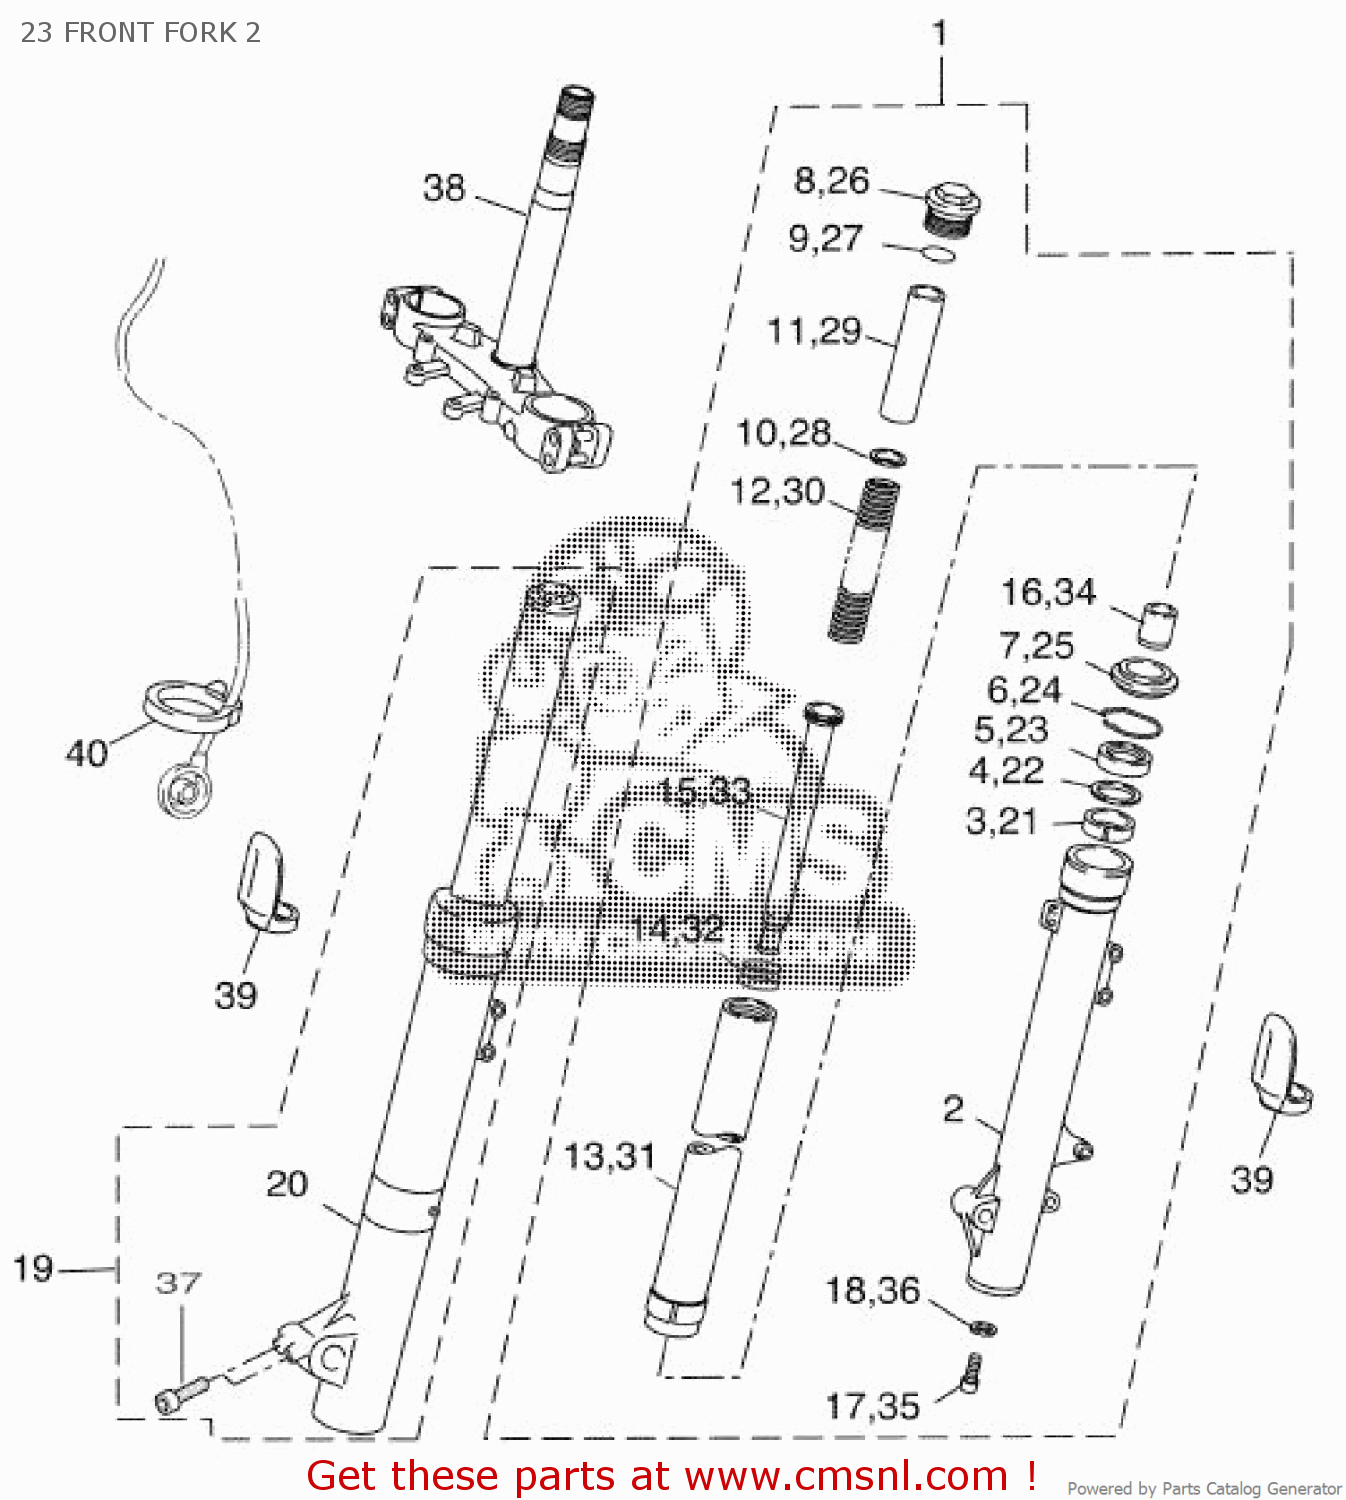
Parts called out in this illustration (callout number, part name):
1	FRONT FORK ASSY (L.H)
2	TUBE, OUTER (LEFT)
3	METAL, SLIDE 1
4	WASHER, OIL SEAL
5	OIL SEAL
6	CLIP, OIL SEAL
7	SEAL, DUST
8	BOLT, CAP
9	O-RING
10	WASHER, SPRING UPPER
11	SPACER
12	SPRING, FRONT FORK
13	INNER TUBE COMP.1
14	PISTON, FRONT FORK
15	CYLINDER COMP., FRONT FORK
16	SPINDLE, TAPER
17	BOLT
18	GASKET (NAS)
19	FRONT FORK ASSY (R.H)
20	TUBE, OUTER (RIGHT)
21	METAL, SLIDE 1
22	WASHER, OIL SEAL
23	OIL SEAL
24	CLIP, OIL SEAL
25	SEAL, DUST
26	BOLT, CAP
27	O-RING
28	WASHER, SPRING UPPER
29	SPACER
30	SPRING, FRONT FORK
31	INNER TUBE COMP.1
32	PISTON, FRONT FORK
33	CYLINDER COMP., FRONT FORK
34	SPINDLE, TAPER
35	BOLT
36	GASKET (NAS)
37	BOLT (401)
38	UNDER BRACKET COMP.
39	COVER
40	HOLDER, CABLE 1
